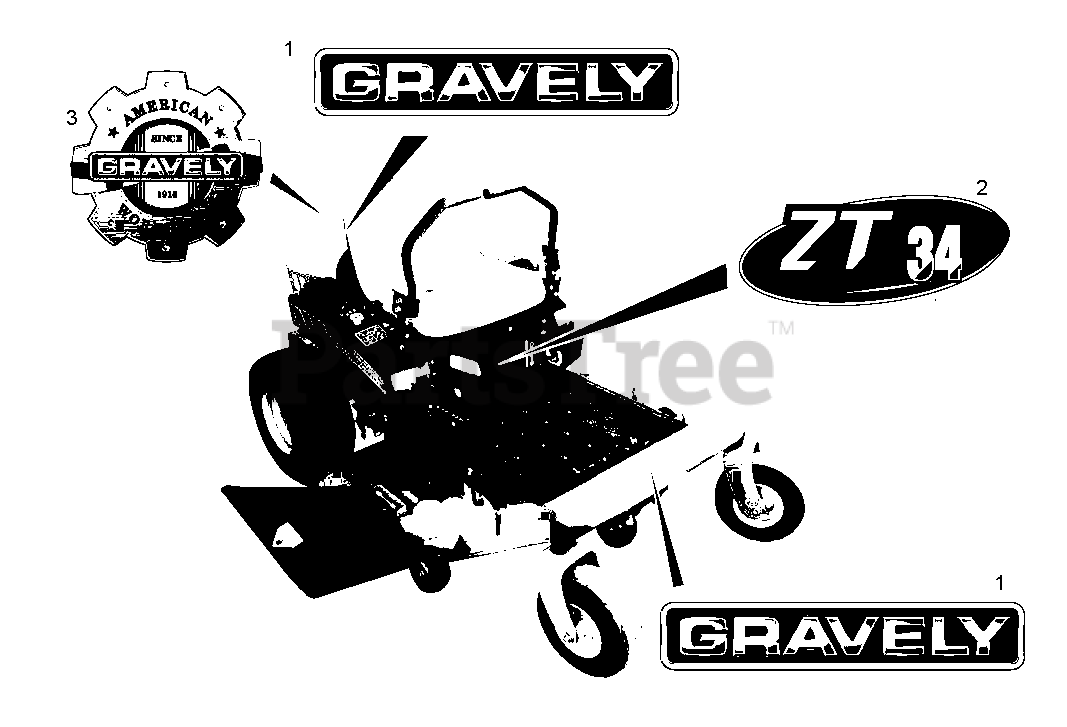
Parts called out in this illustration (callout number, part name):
1	Decal, 9.5" Gravely Logo
2	Decal, ZT 34 (915327)
3	Decal, Gravely Heritage, Large
